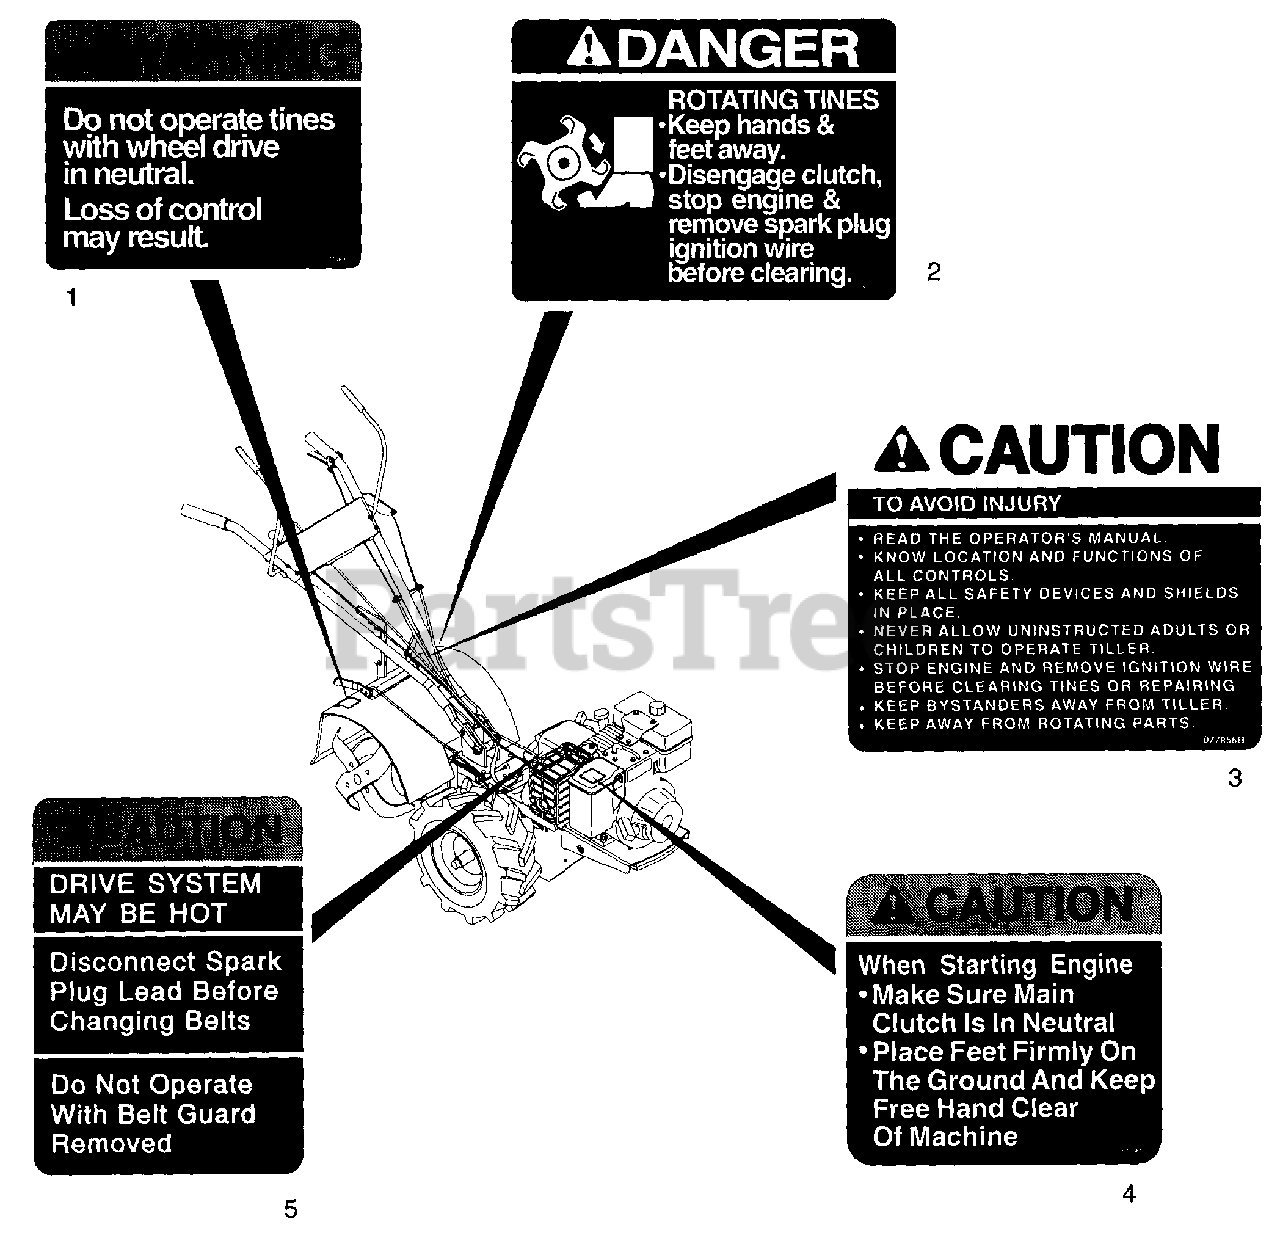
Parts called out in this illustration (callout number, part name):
1	DECAL - WARNING
2	DECAL - DANGER ROTATING TINES
3	DECAL-CAUTION TO AVOID INJURY
4	CAUTION DECAL
5	CAUTION DECAL
